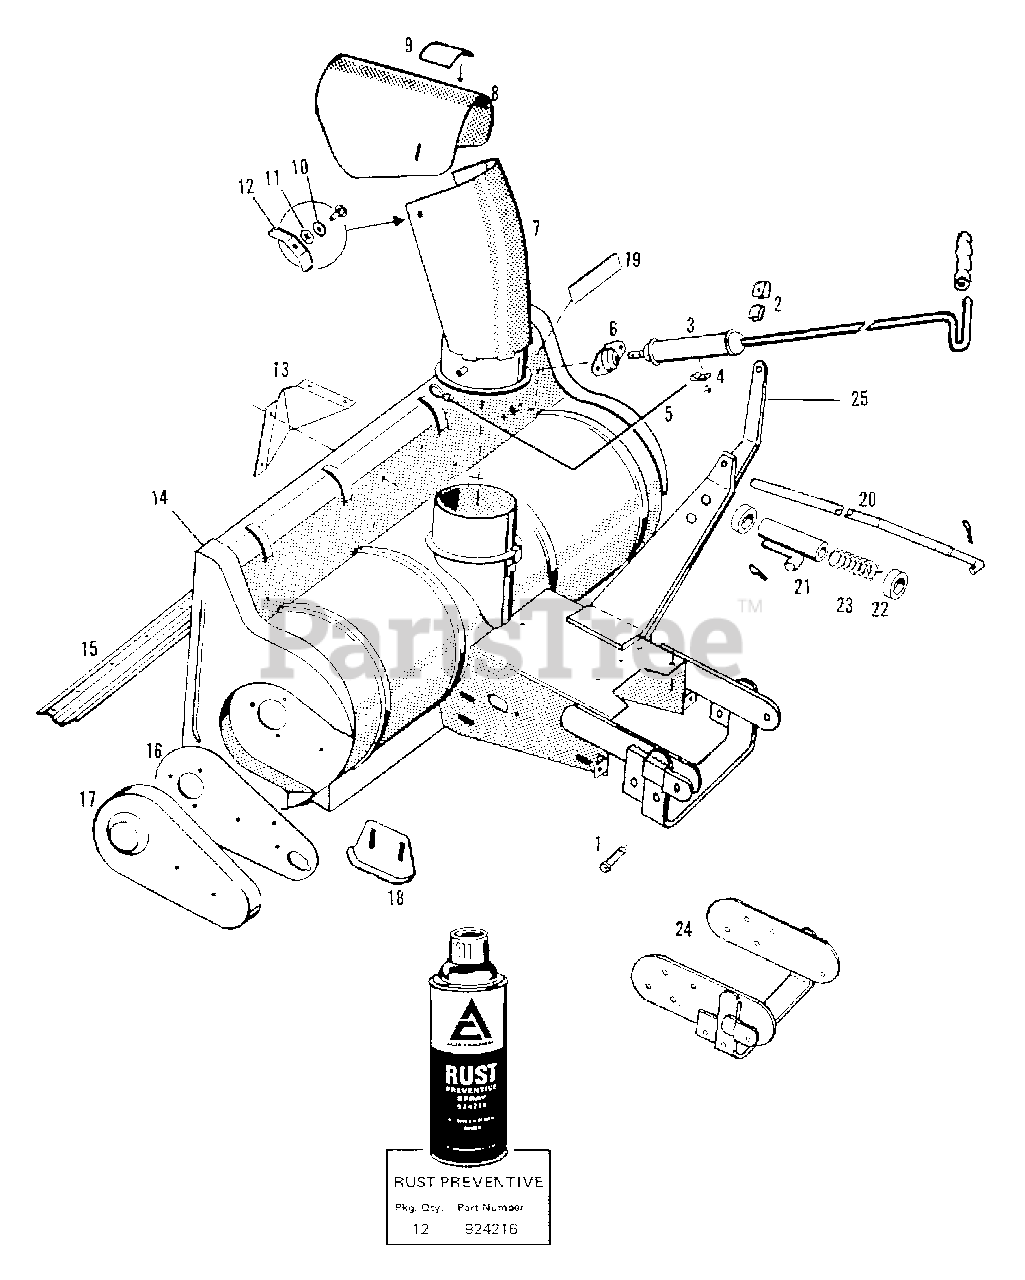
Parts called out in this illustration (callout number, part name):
1	PIN, Hitch
1	PIN, Quick
2	GUIDE, Control Rod
2	LINER, Rod Guide
2	CAPSCREW, 5/16NC x 1-1/4
2	NUT, 5/16NC, Lock
2	PIN, 3/32 x 1", Cotter (Eff. S/N 1001)
3	LEVER ASSEMBLY, Spout Control
3	GRIP, Handle
3	PIN, 3/32 x 1", Cotter
4	CLAMP, Cable
4	SCREW, 1/4NC x 3/8 Tapping
5	CABLE ASSEMBLY, Spout Control
5	WASHER, 1/4 Plain
5	LOCKWASHER, 5/16
5	NUT, 5/16NC
6	BEARING ASSEMBLY, Flange
6	CAPSCREW, 1/4NC x 5/8
6	LOCKWASHER, 1/4
6	NUT, 1/4NC
7	SPOUT ASSEMBLY, Thrower
8	EXTENSION, Spout
8	BOLT, 5/16NC x 3/4
8	WASHER, 3/8
9	DECAL, A-C Emblem
10	WASHER, Cup
11	LOCKWASHER, Special, Hexagon
12	NUT, Wing
13	DEFLECTOR
13	CAPSCREW, 5/16NC x 5/8
13	LOCKWASHER, 5/16
13	NUT, 5/16NC
14	HOUSING ASSEMBLY, 36" Thrower (Eff. S/N 1001)
14	HOUSING ASSEMBLY, 42" Thrower (Eff. S/N 1001)
15	SCRAPER, Snow, 36" Thrower
15	SCRAPER, Snow, 42" Thrower
15	CAPSCREW, 5/16NC x 5/8
15	WASHER, 1/4
15	NUT, 1/4NC
16	PLATE, L.H., Side
16	CAPSCREW, 1/4NC x 5/8
16	WASHER, 1/4NC, Lock
16	NUT, 1/4NC, Lock
17	GUARD, Chain
18	SKID, Shoe (Eff. S/N 1001)
18	SKID, Shoe (Prior S/N 1001)
18	BOLT, 3/8NC x 3/4
18	WASHER, 3/8
18	LOCKWASHER, 3/8
18	NUT, 3/8NC
19	DECAL, Safety
20	ARM, Front Lift
20	PIN, Quick
21	GUIDE ASSEMBLY, Rod
21	PIN, Quick
22	COLLAR, Set
22	SETSCREW, 5/16NC x 1/2
24	HITCH ASSEMBLY, (Eff. S/N 1001)
24	CAPSCREW, 7/16 x 1
24	NUT, 7/16NC, Lock
25	LEVER, Lift
25	CAPSCREW, 3/8NC x 1
25	NUT, 3/8NC
